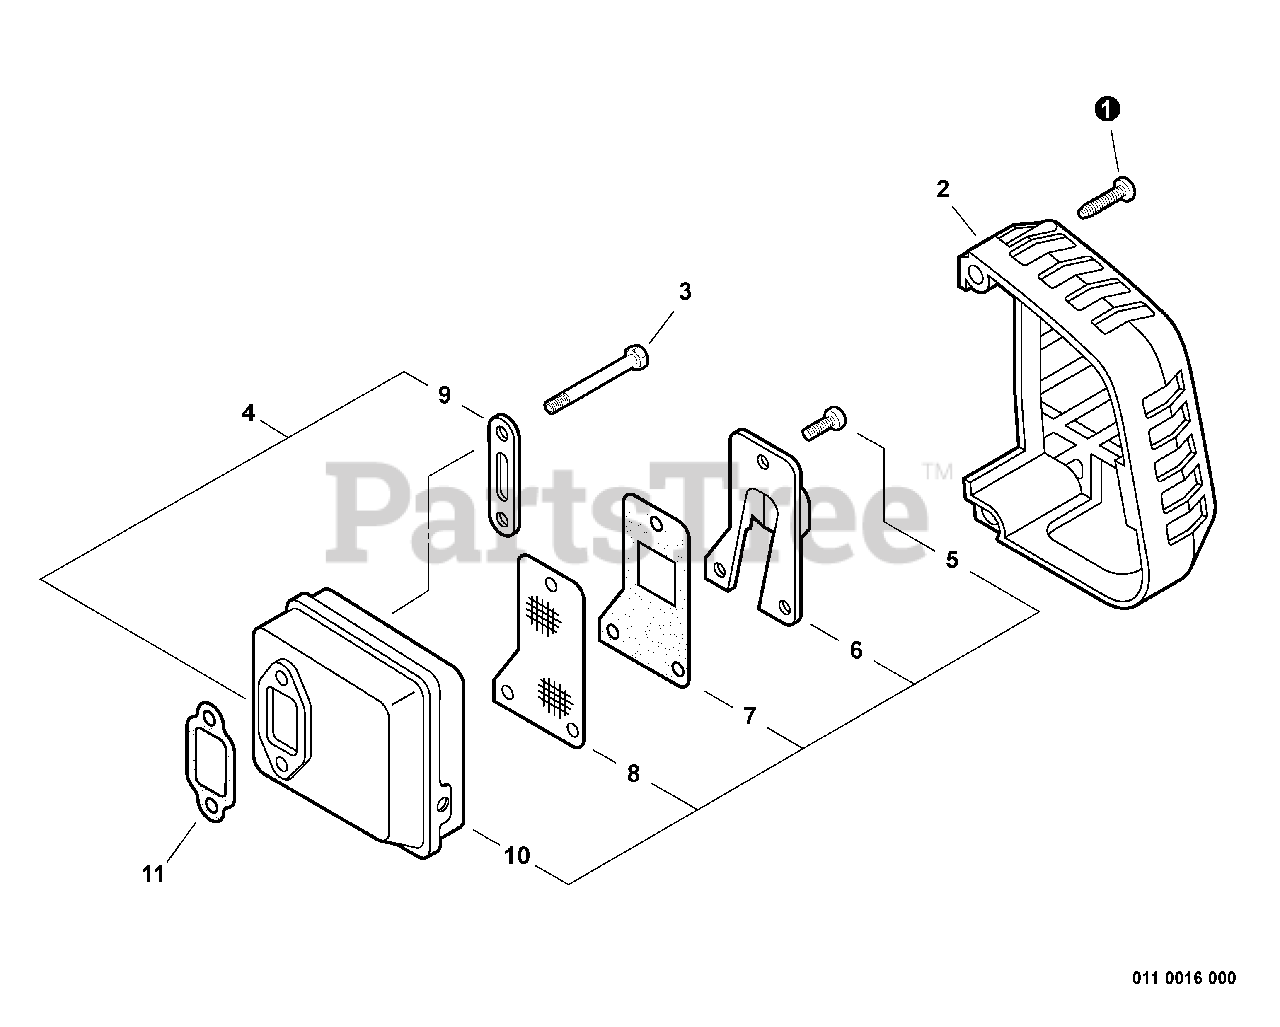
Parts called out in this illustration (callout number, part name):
1	SCREW - 5X20 -- TAPPING
2	COVER, EXHAUST
3	BOLT - FLANGE
4	MUFFLER KIT
5	SCREW - 4X10
6	GUIDE, EXHAUST
7	GASKET, EXHAUST
8	SCREEN, SPARK ARRESTOR
10	MUFFLER
11	GASKET, EXHAUST
